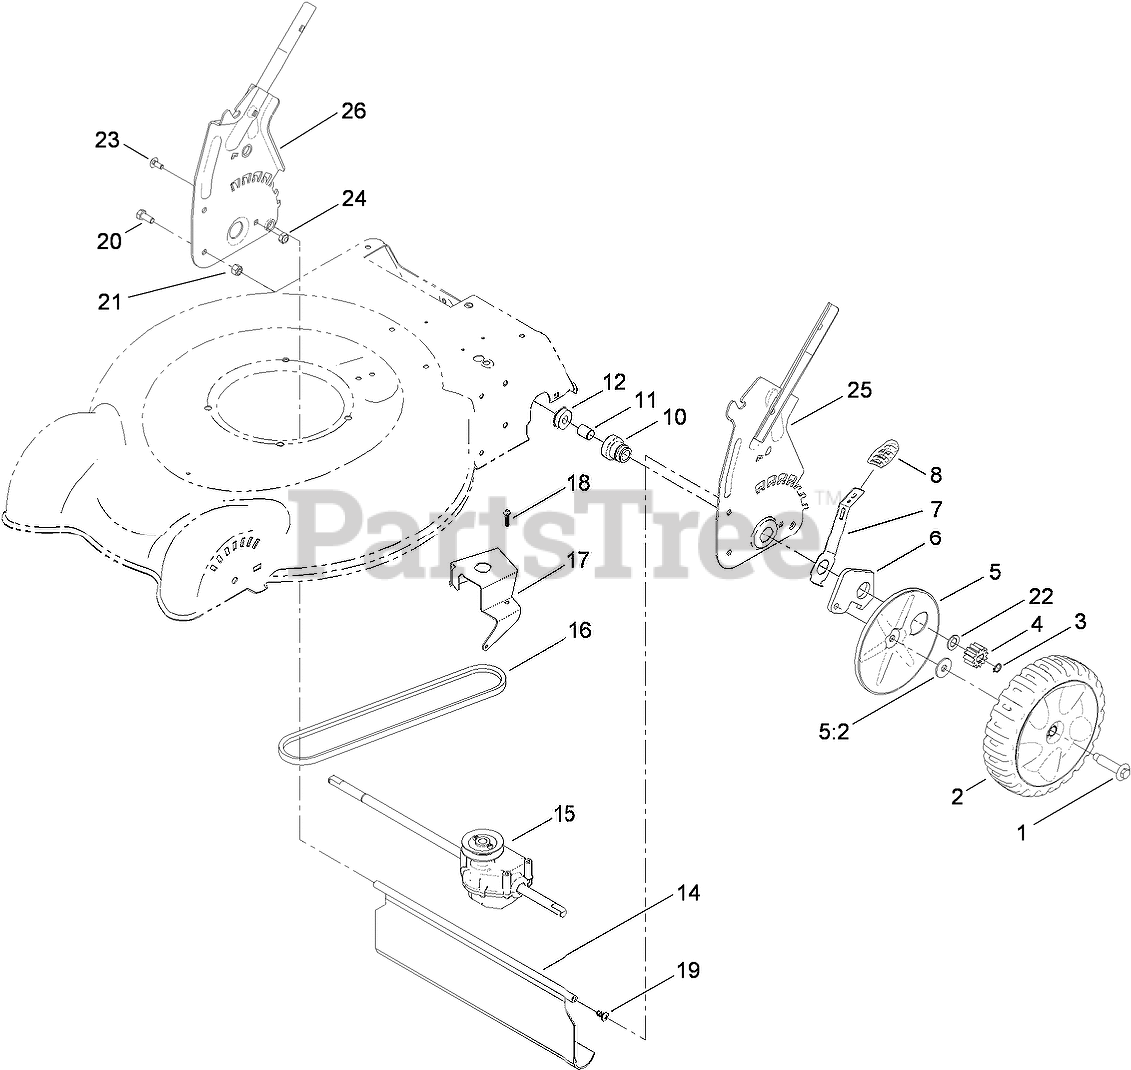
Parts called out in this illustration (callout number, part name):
1	BOLT-SHOULDER
2	8 INCH WHEEL GEAR ASM
3	RING-RETAINING
4	GEAR-PINION
5	WHEEL COVER ASM
5:2	WASHER-STEPPED
6	ARM-PIVOT, REAR
7	ARM-SPRING
8	Knob-Lever, HOC
10	RETAINER-BUSHING, HOC
11	BUSHING-SLEEVE
12	BEARING-BALL
14	SHIELD-TRAILING
15	TRANSMISSION ASM
16	V-BELT
17	BRACKET-TRANSMISSION
18	SCREW-PLASTITE
19	SCREW-PTH
20	SCREW-HH
21	NUT-LOCK, NI
22	WASHER-THRUST
23	SCREW-CARR
24	NUT-LOCK, NI
